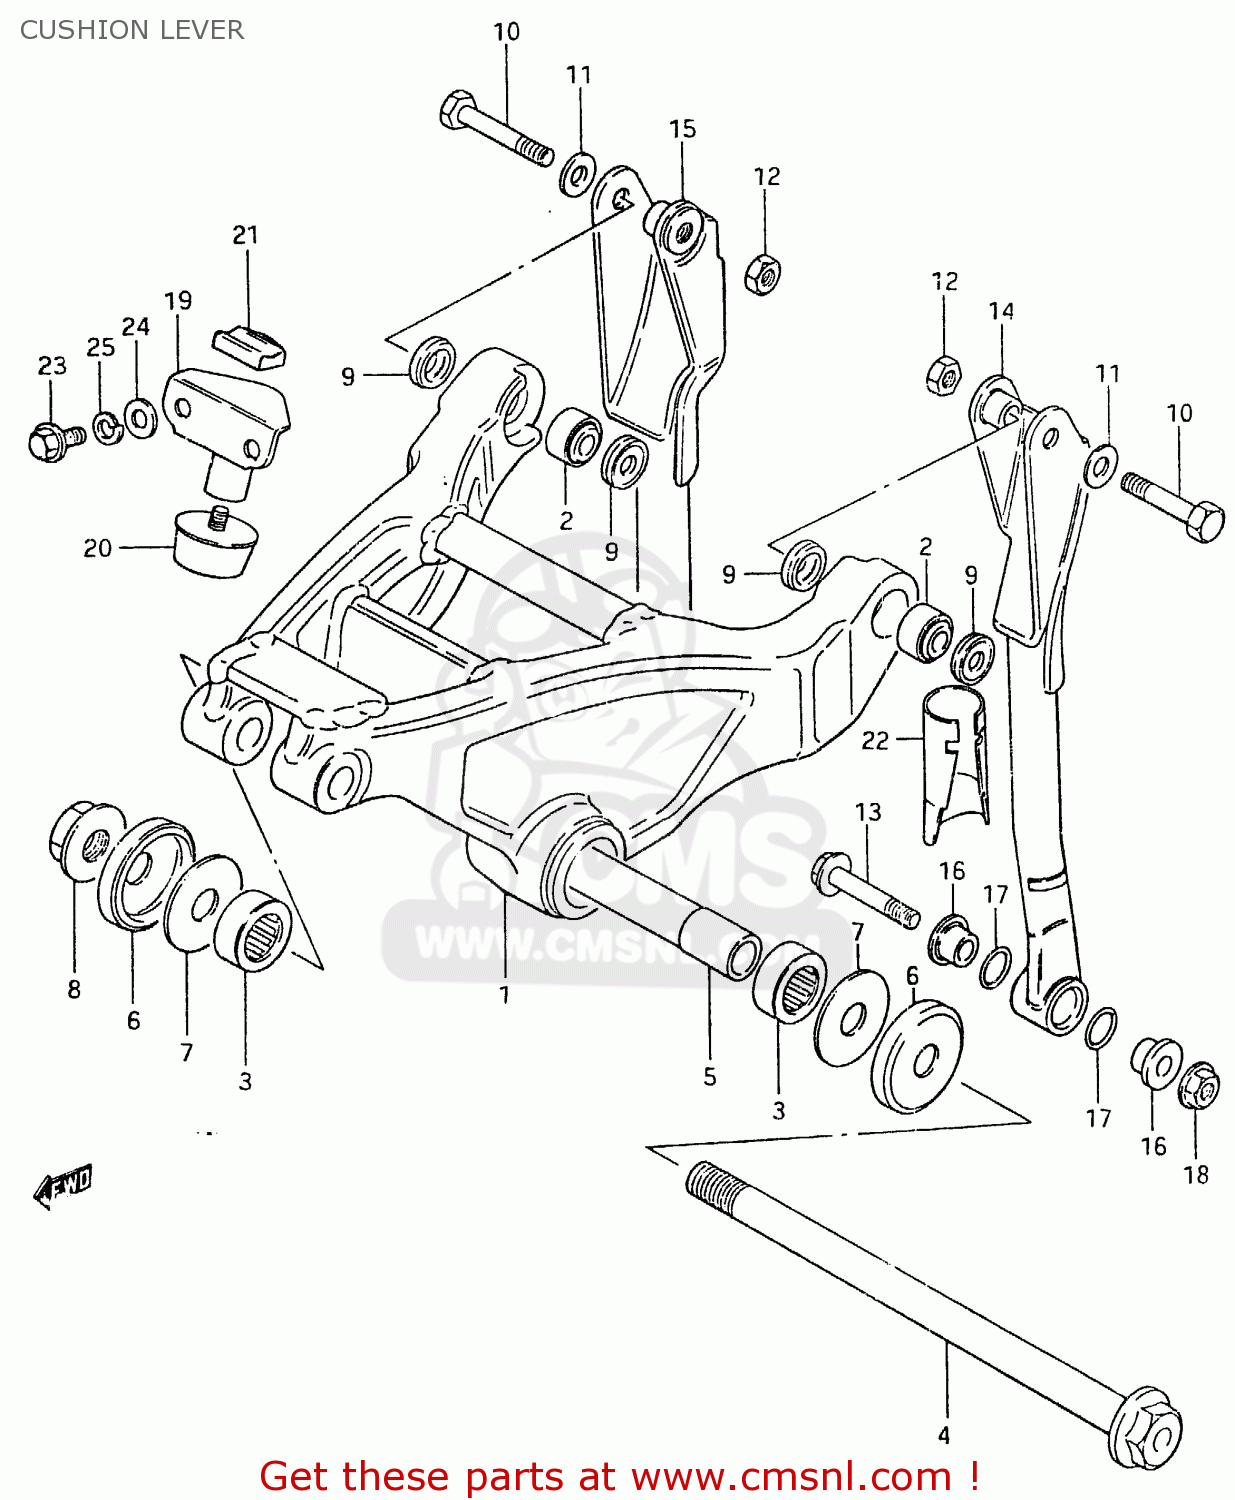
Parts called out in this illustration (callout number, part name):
1	LEVER SET,REAR CUSHION
2	BEARING(8X18X11)
3	BEARING(17X26X20)
4	SHAFT,REAR CUSHION LEVER
5	SPACER,REAR CUSHION LEVER
6	SEAL,REAR CUSHION LEVER
7	WASHER(12X35X2)
8	NUT 12MM
9	DUST SEAL,RR CUSHION LOD UPR.
10	BOLT 8X38
11	WASHER
12	NUT
13	BOLT 8X45
14	ROD,REAR CUSHION LEVER
15	BOLT,REAR CUSHION LEVER
16	SPACER,RR CUSHION ROD LWR
17	O RING(D:1.9,ID:13)
18	NUT
19	STOPPER,TENSION
20	RUBBER,TENSION STOPPER
21	SUPPORT RUB TENS
22	PROTECTOR,REAR CUSHION R
23	BOLT
24	WASHER
25	LOCK WASHER
